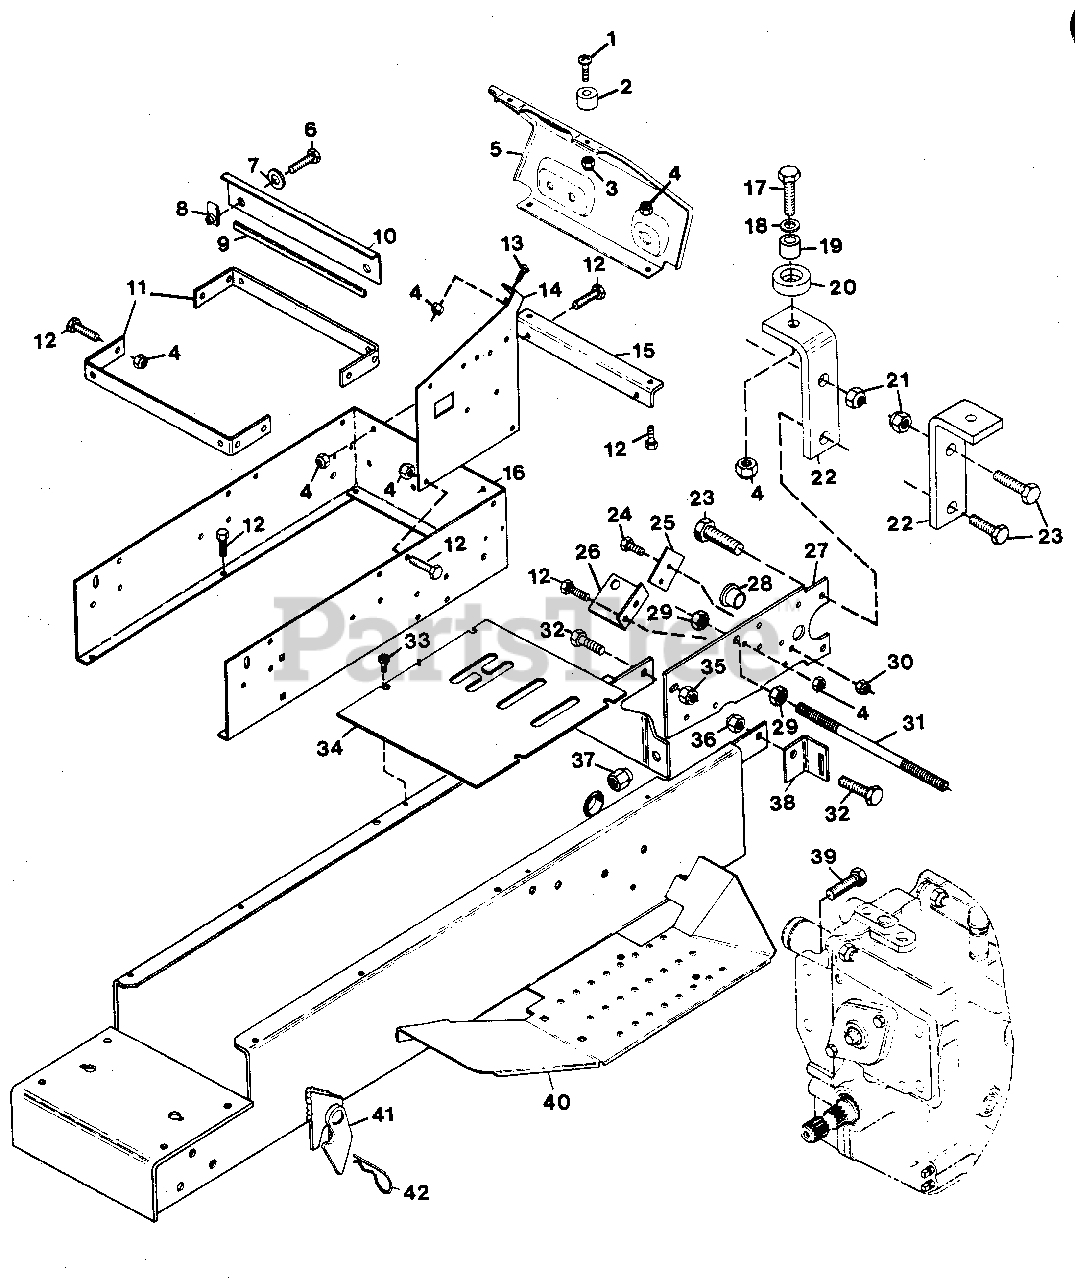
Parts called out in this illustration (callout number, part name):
1	SCREW, MACHINE 6-32X.625 PHD
2	BUMPER
3	NUT, MACHINE LOCK 6-32
4	NUT LOCK 1/4-20
5	PANEL, INSTRUMENT
6	BOLT, HEX 1/4-20X.875
7	WASHER, FLAT .281X.625X.065
8	NUT, RETAINER
9	MOULDING
10	BRACKET, FORWARD TANK
11	BRACKET, FUEL TANK
12	BOLT, HEX 1/4-20X.75
13	SCREW, MACHINE 1/4-20X.75 PHD
14	BRACE, INSTRUMENT PANEL L.H.
14	BRACE, INSTRUMENT PANEL R.H.
15	BRACKET, INSTRUMENT PANEL
16	SUPPORT, INSTRUMENT PANEL
17	BOLT, HEX 1/4-20X1.25
18	WASHER, FLAT .312X.734X.065
19	BUSHING, .259X.375X.25
20	BUMPER, SEAT
21	NUT, LOCK 1/2-13
22	BRACKET, REAR HITCH
23	BOLT, HEX 1/2-13X1.50
24	BOLT, HEX 5/16-18X.75
25	BRACKET, BUSHING LOCK
26	BRACKET, INTERLOCK SWITCH
27	PLATE, FWD-REV MOUNTING
28	BUSHING, NYLON .76X1.00X.76 FLG
29	NUT, HEX 1/2-13
30	NUT, LOCK 5/16-18
31	ROD, FRAME EXTENSION BRACE
32	BOLT, HEX 3/8-16X1.25
33	SCREW, TAPPING 1/4-20X.625 PHD
34	PLATE, MANUAL CONTROL COVER
34	PLATE, HYDRAULIC CONTROL COVER
35	NUT, LOCK 3/8-16
36	NUT, LOCK 3/8-16
37	NUT, RIM
38	BRACKET, FENDER HOLD-UP
39	BOLT, HEX 1/2-20X1.50
40	WELDMENT, FRAME
41	WELDMENT, MOWER BRACKET R.H.
41	WELDMENT, MOWER BRACKET L.H.
42	PIN, HAIR
